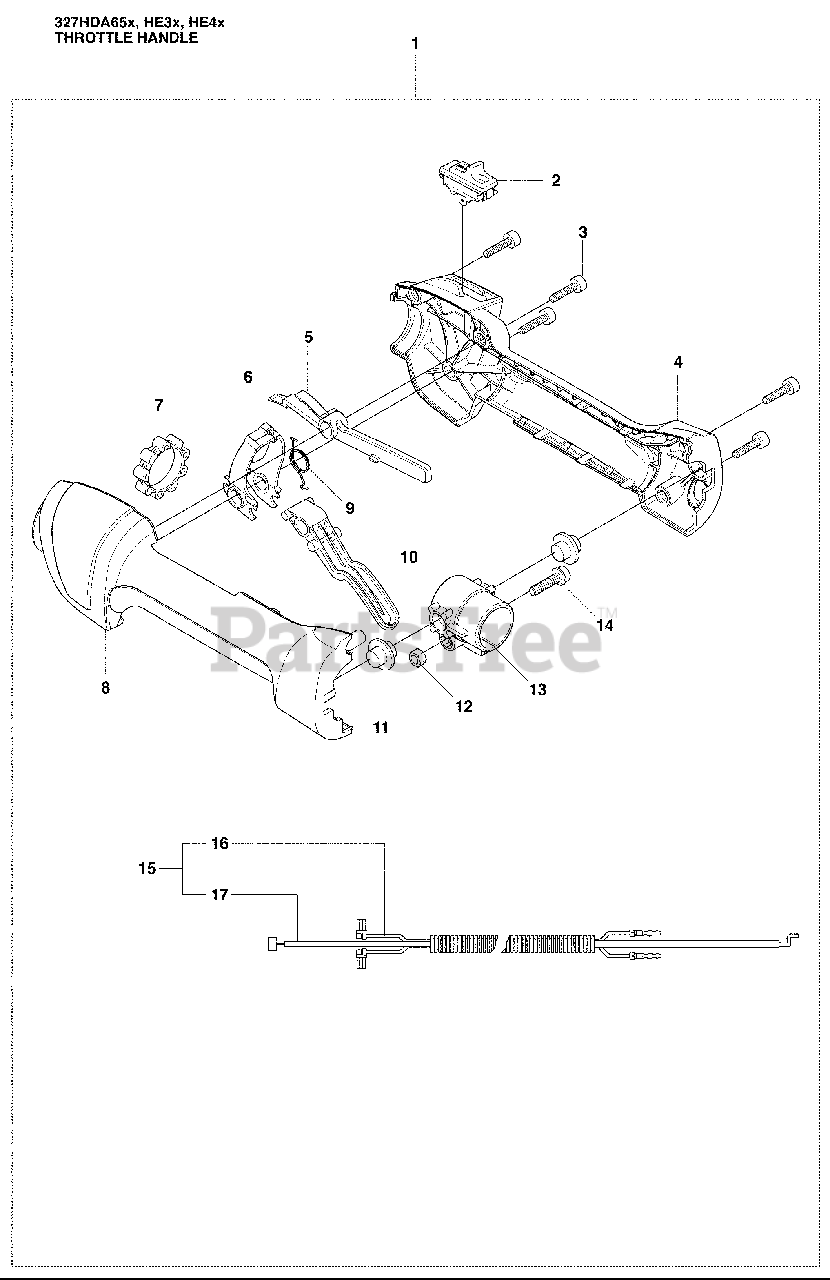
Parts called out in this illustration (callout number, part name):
2	Stop Button
5	Throttle Lock
7	Vibration Damper
9	Return Spring
10	Throttle Trigger
11	Vibration Absorber
12	Hex Nut, M5 X .80 DIN
16	Short-Circuit Cable
17	Throttle Wire Assembly
